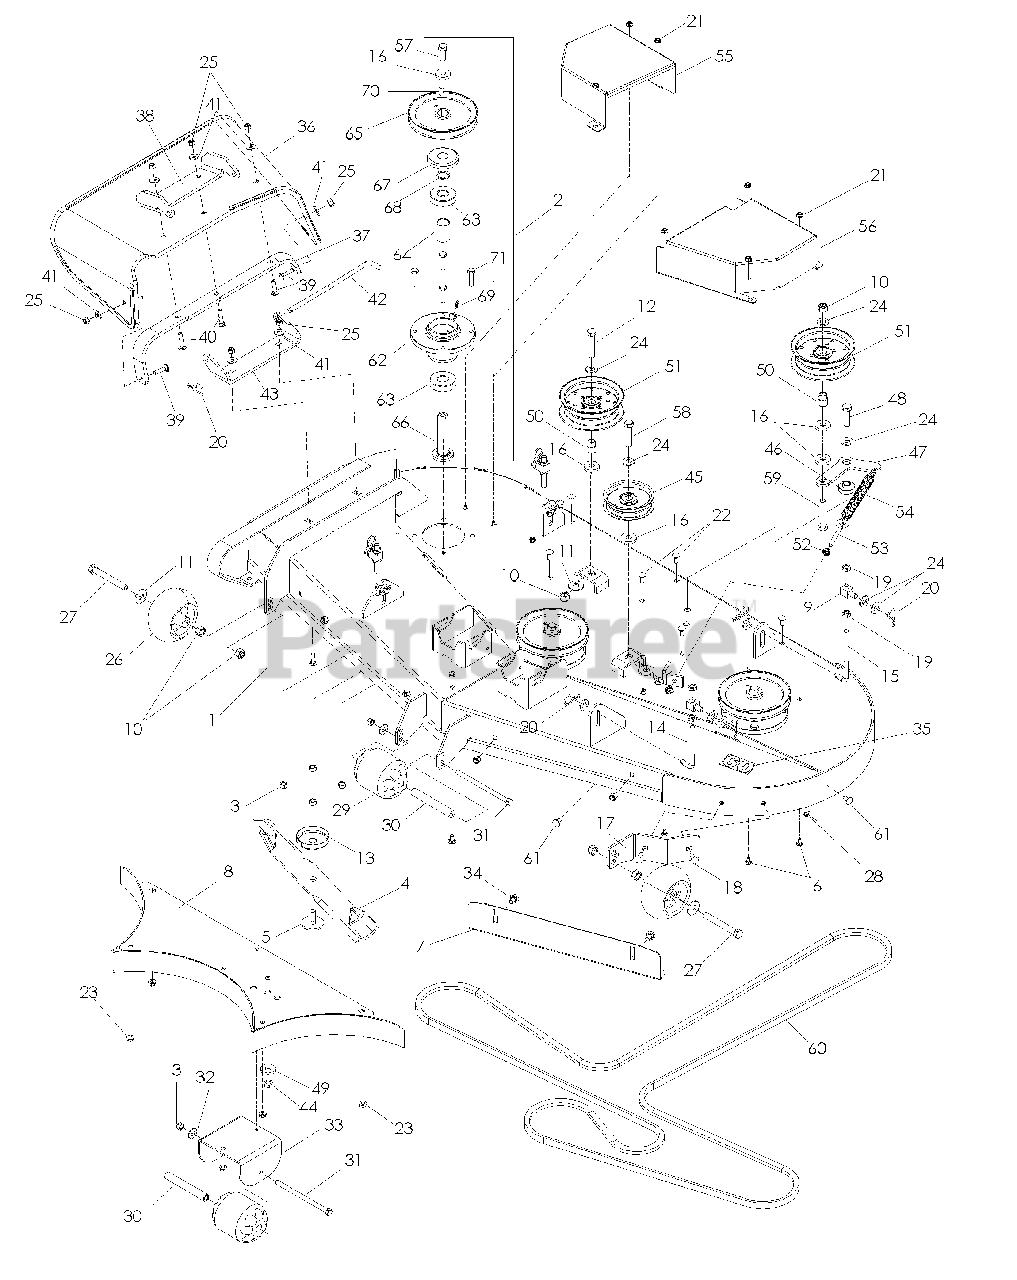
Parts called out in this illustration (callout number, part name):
1	DECK W/DECALS, 60" DIX
2	SPINDLE ASSEMBLY
3	NUT 3/8-16 NYLOC
4	BLD 60" HI LIFT FUSION
5	BLADE BOLT
6	RHSSNB 1/4-20 X 1/2
7	BLOW BY BAFFLE
8	60 W-BAFFLE WLDT.
10	NUT 1/2-13 HEX NYLOC ZD
11	WASH USS FLAT 1/2
12	1/2-13X2-1/2 HHB GR5
13	TRASH GUARD
14	L BOLT, S
15	L BOLT, L
16	WASHER .525 X 1.375 X .25
17	BRACKET
18	RHSSNB 5/16C X 1.0
19	7/16-14UNC HX JAMNUT
20	PIN, COTTER 1 3/4
21	NUT 1/4-20 HEX FLG LK ZD
22	RHSNB 5/16C X 1
23	5/16-18 FLANGED L-NUT
24	WASHER 1/2" FLAT
25	NUT 5/16 NYLOC
26	GAUGE WHEEL
27	HHB, 1/2-13X4
28	5/16-18 THIN PROF NY
29	ROLLER 3-3/4 DIA. X 4-1
30	BUSHING
31	3/8-16 X 6-1/2 HHB GR8
32	WASHER 3/8 FLAT
33	REAR CENTER ROLLER BKT 60 BLK
34	RHSNB 3/8-16 X 3/4 GR5 ZD
35	DECAL, 60"
36	CHUTE, RUBBER DISCHARGE 60"
37	BRKT REINF-CHUTE 60"
38	PIVOT BRKT RUBBER CHUTE
39	BOLT, CARRIAGE 5/16X1-1/4
40	RHSNB 5/16-18 X 1-1/2 GR 5 ZD
41	WASHER 5/16 FLAT
42	DEFLECTOR PIN
43	PIVOT BRACKET - DECK
44	NUT, 1/2-13 THIN PROF NYL
45	PULLEY IDLER
46	IDLER SPACER
47	IDLER ARM
48	1/2-13X1-3/4 HHB GR. 5
49	WASHER-.533IDX1.37OD
50	SPACER - IDLER
51	PULLEY, IDLER
52	NUT 5/16C WHIZ
53	EYE BOLT 5/16 X 3.50
54	SPRING, DECK BELT
55	PULLEY GUARD RH 60 PAINTED
56	PULLEY GUARD LH 60 PAINTED
57	1/2-20 UNF X 1 1/4 HHBLT
58	HEX SCREW-.5C X 2.25
59	HCS 1/2C X 2 3/4
60	BELT, DECK
61	CARRIAGE BOLT 5/16C X 5/8"
62	DECK HUB MACHINED
63	BEARING - 6305 - 2RS
65	PULLEY 6.45 METRIC
66	SHAFT SHORT
67	TRASH GUARD
68	HUB PULLEY SPACER
69	ZERK, 3/16, DRIVE IN
70	OUTER SHAFT KEY
71	HHB 3/8-16X1-1/2 GR5
